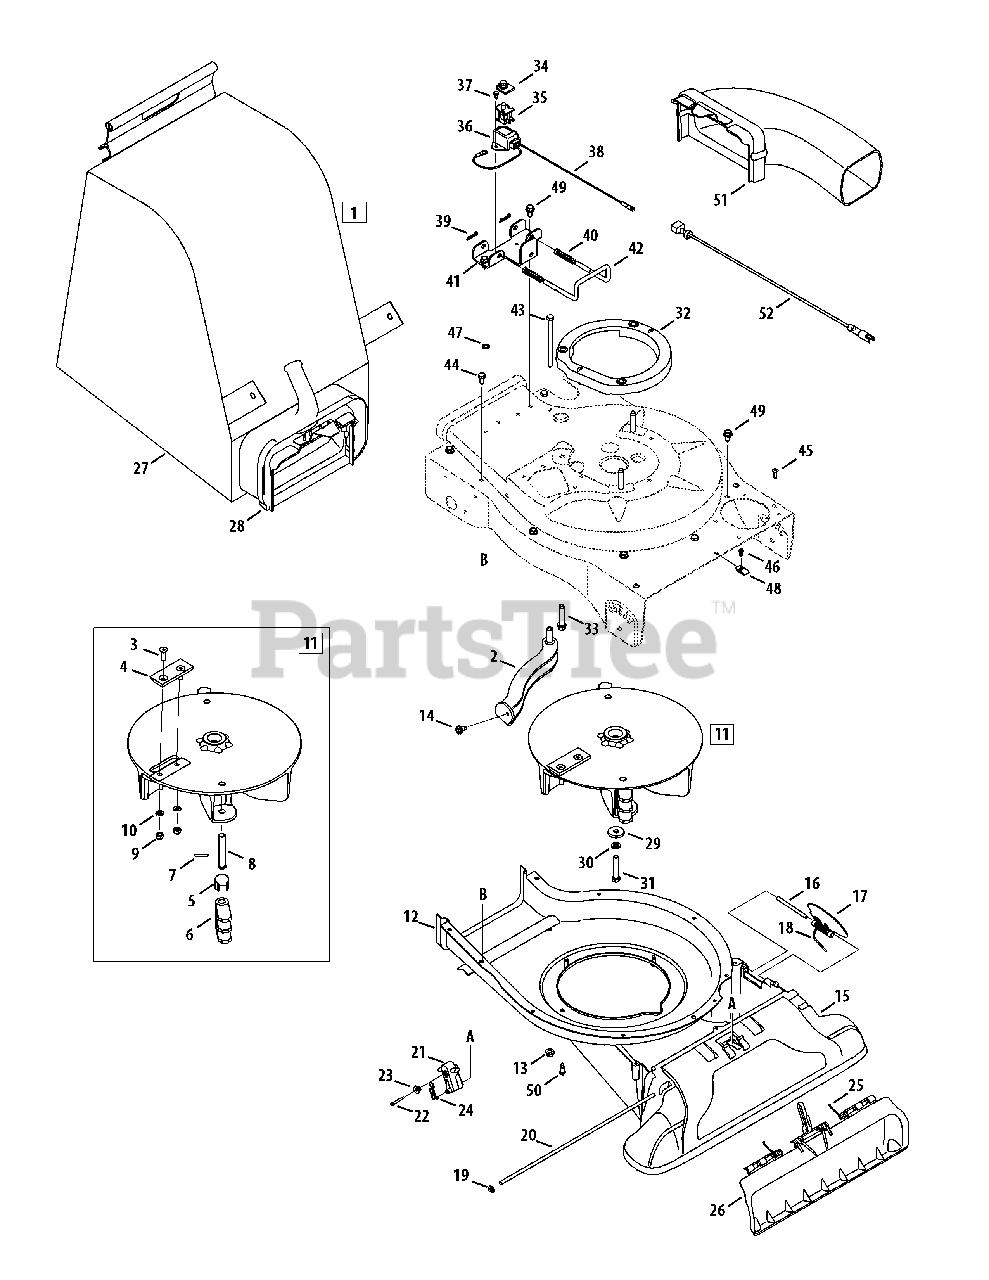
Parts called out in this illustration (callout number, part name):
1	Bag Assembly
2	Screen Assembly
3	Hex Screw 5/16-24 x 1.0
4	Chipper Blade
5	Pin Clip
6	Flail
7	Spiral Pin
8	Clevis Pin
9	Lock Nut, 5/16-24
10	Lock Washer, 5/16
11	Impeller Assembly
12	Lower Flail Housing
13	Flange Lock Nut 5/16-18
14	Screw, 5/16-18 x.500
15	Nozzle (Incl. Ref.# 16-26)
16	Hinge Pin
17	Base Adapter Door
18	Torsion Spring
19	Cap Speed Nut 1/4
20	Pivot Rod
21	Nozzle Door Lever
22	Hex Screw, #8-18 x 1.25
23	Shoulder Spacer
24	Extension Spring
25	Nozzle Door Torsion Spring
26	Nozzle Door
27	Bag
28	Chute Assembly
29	Flat Washer.375 ID x 1.25 OD
30	Lock Washer 3/8
31	Hex Cap Screw, 3/8-24 x 2.75
32	Engine Spacer Assembly
33	Screw, 3/8-16 x 1.875
34	Switch Cover
35	Safety Switch
36	Safety Switch Cover
37	Hex Washer Screw #10-16 x.50
38	Wire Harness
39	Cotter Pin
40	Compression Spring
41	Mounting Bracket
42	Lock Rod
43	Hex Cap Screw 5/16-18 x 4.5
44	Hex Cap Screw 5/16-18 x.625
45	Screw, #12-16 x.750
46	Screw #10 - 16 x.500
47	External L-Washer 5/16
48	Speed Nut
49	Hex Index Screw, 5/16-12 x.750
50	Shoulder Screw, #12-24 x .30 x .46
51	Blower Chute
52	Wire Harness Adapter
